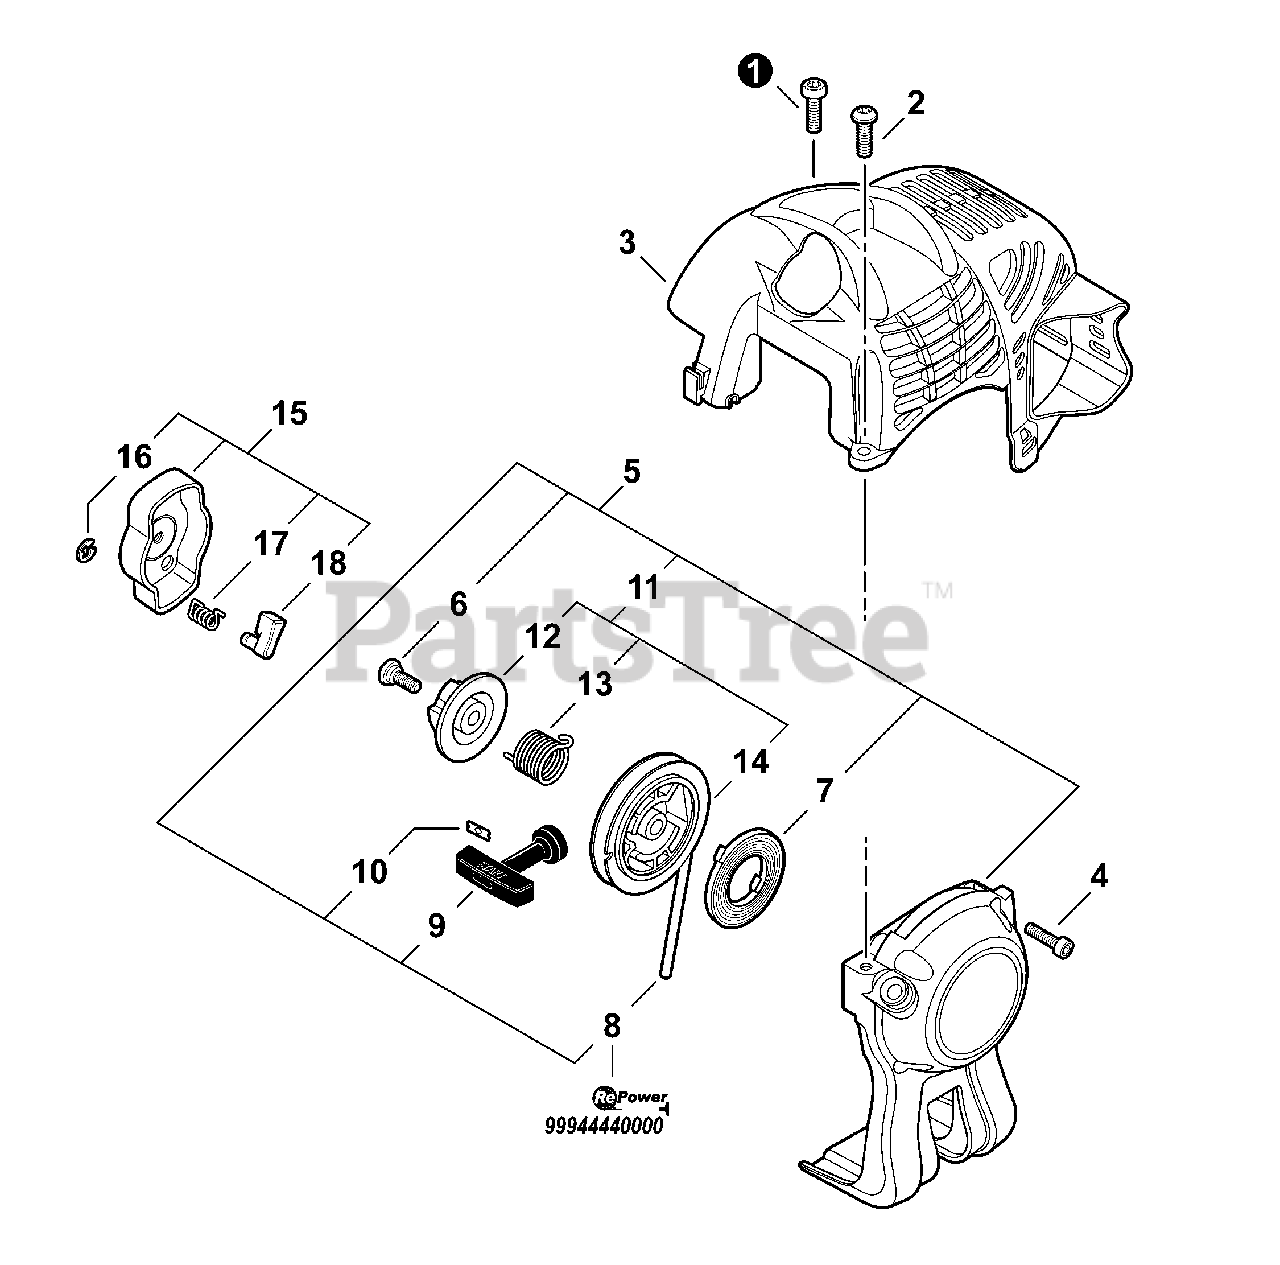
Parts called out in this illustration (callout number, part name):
1	BOLT, TORX 5×16
2	BOLT, TORX 5×16
3	COVER, ENGINE
4	BOLT, TORX 4×16
5	STARTER ASSY, RECOIL
6	SCREW
7	SPRING, RECOIL
8	ROPE, STARTER
9	GRIP, STARTER
10	RETAINER, ROPE
11	REEL/CAM PLATE SET
12	PLATE, CAM
13	SPRING, TORSION
14	REEL, ROPE
15	PAWL ASSY, STARTER
16	E-RING 4
17	SPRING, RETURN
18	PAWL, STARTER
